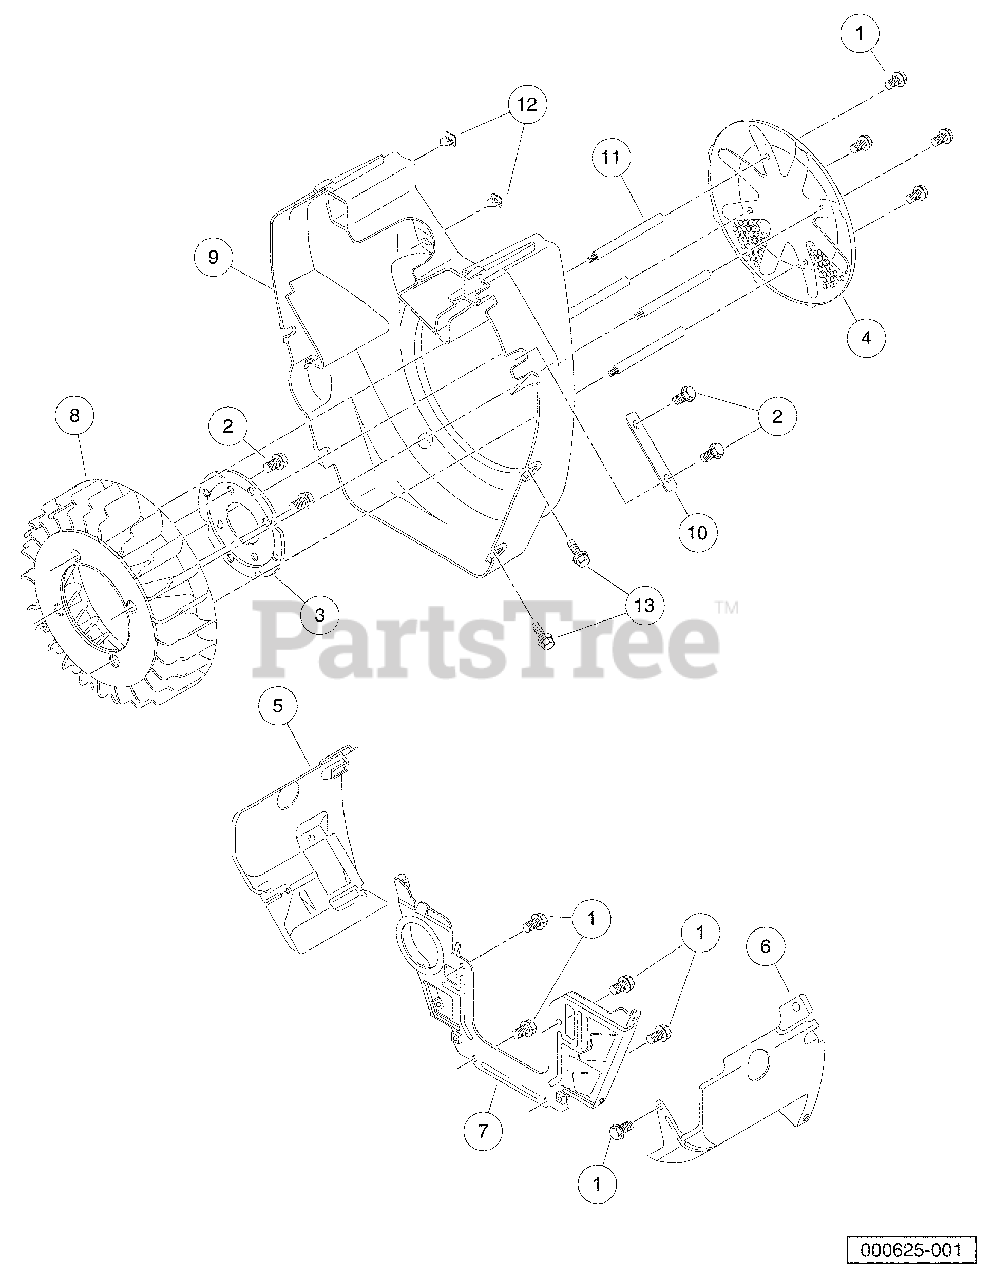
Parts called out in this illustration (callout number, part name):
1	Bolt, Flg, M6 X 1.0 X 12
2	Bolt, Flg, M6 X 1.0 X 16
3	Plate, Housing, Fan, Fh
4	Screen, Fan, Fh
5	Shroud, Engine, Rh, Fh
6	Shroud, Engine, Lh, Fh
7	Shroud, Engine, Front, Fh
8	Fan, Cooling, Fh
9	Housing, Engine, Fh
10	Washer, Housing, Fan, Fh
11	Stud, Fan Screen, Fh
12	Nut, Press In, Front Cover, Fh
13	Bolt, Oil Pickup, Fh
